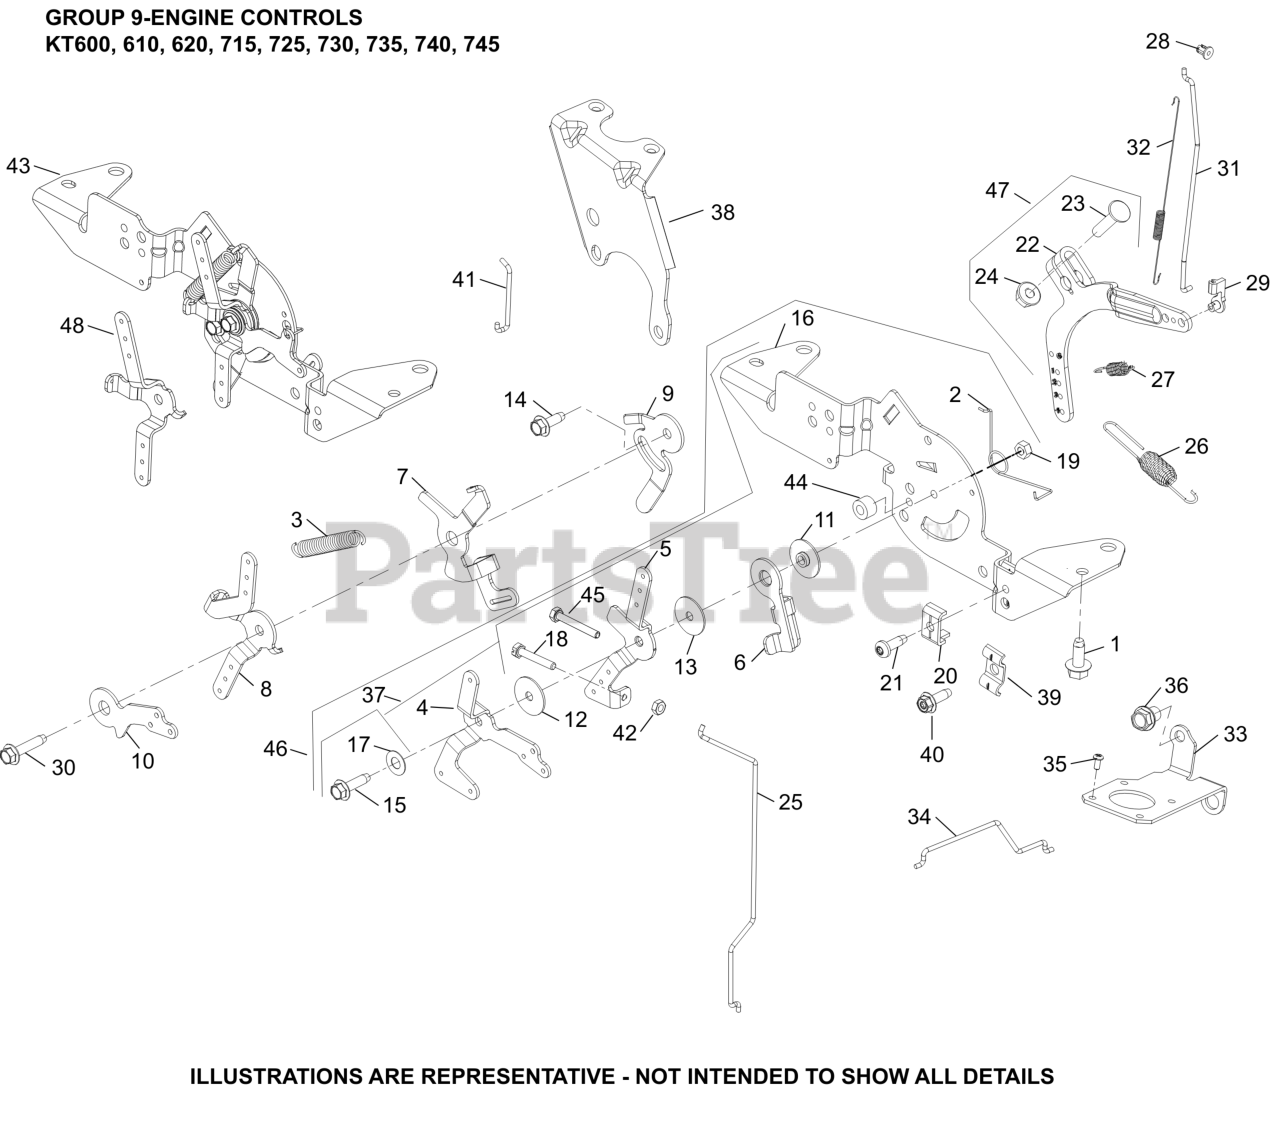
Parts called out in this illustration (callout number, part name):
1	SCREW, THREAD FORMING
2	SPRING, CHOKE RETURN
4	LEVER, CHOKE
5	LEVER, THROTTLE CONTROL
6	LEVER, THROTTLE ACTUATOR
11	SPACER, CONTROL ASSEMBLY
12	WASHER, FLAT 5.5 MM
13	WASHER, FLAT 5 MM
14	SCREW, THREAD FORMING
15	SCREW, THD FRM-USE 25 086 473-S
16	BRACKET, SPEED CONTROL
17	WASHER, SPRING 1/4"
18	SCREW, SLT HD CAP M4X0.7X25
19	NUT, LOCK M5X.8
20	CLAMP, CABLE CABLE
22	LEVER, GOVERNOR - (#2409069S)
23	BOLT, RD HD SQ NECK M6X1.0X25
24	NUT, FLG M6X1.0
25	LINKAGE, CHOKE
26	SPRING, GOVERNOR (ORANGE)
27	SPRING, GOVERNED IDLE
28	BUSHING, LINKAGE RETAINING
29	BUSHING, THROTTLE LINKAGE
32	SPRING, LINKAGE
34	LINKAGE, THROTTLE
40	SCREW, THREAD FORMING
42	NUT, M4X0.7
46	CONTROL ASSEMBLY, DUAL WIRE
47	LEVER, GOVERNOR ASSEMBLY
